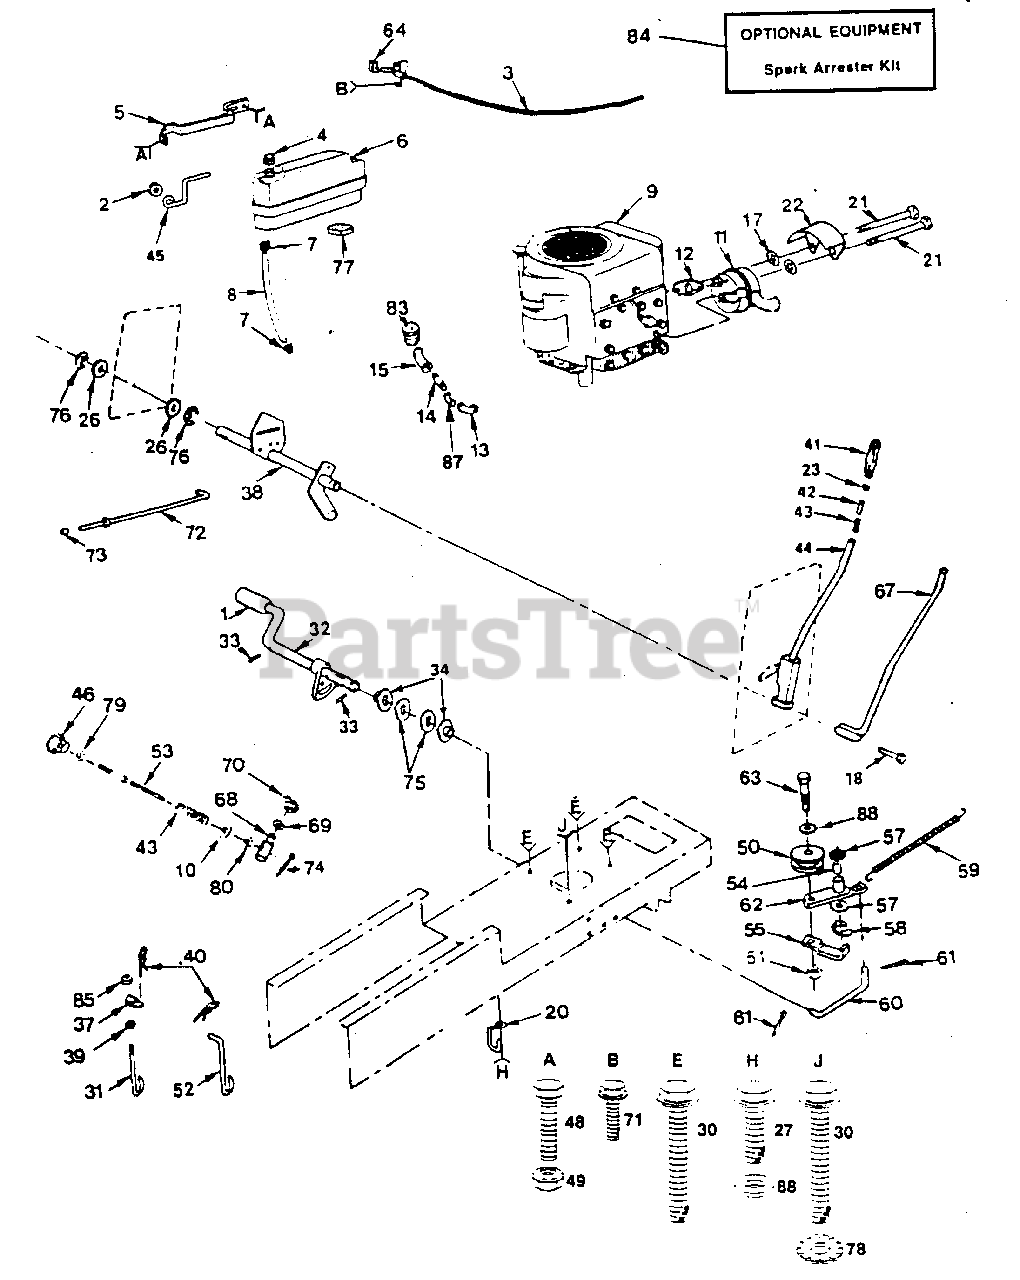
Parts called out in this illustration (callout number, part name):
1	Cover, Pedal
2	Washer, 13/32 x 13/16 x 14 Ga.
3	Control, Throttle
4	Cap, Fuel
5	Support, Tank, Fuel
8	Line, Fuel
9	Engine, Briggs & Stratton, Model No. 281707, Type No. 1413-01
10	Washer 13/32 x 5/8 x 16 Ga.
12	Gasket, Exhaust
13	Elbow, Street
14	Nipple, Pipe, STD 3/8-18 NPT x 3-1/2
15	Elbow, STD 90ø 3/8-18 NPT
17	Washer 15/32 x 1 x 16 Ga.
18	Bolt, Hex 3/8-16 x 1-1/2
20	Retainer, Belt, Chassis, L.H.
21	Bolt, Shoulder
22	Shield, Heat, Muffler
23	Button, Plunger
26	Washer 29/32 x 1-1/4 x 16 Ga.
27	Screw, Hex, Washer Hd., Thd. Roll. 3/8-16 x 3/4
30	Screw, Hex, Washer Hd., Thd. Roll. Type TT 3/8-16 x 1-1/4
31	Link, Lift, Adjustable
32	Shaft, Pedal, Foot
33	Pin, Roll 3/16 x 1
34	Bearing, Nylon
37	Trunnion, Lift
38	Shaft Assembly, Lift
39	Nut, Hex, Jam 7/16-20
40	Retainer, Spring
41	Grip, Handle
42	Plunger, Lever, Hand
43	Spring
44	Lever Assembly, Hand Kit (Inc. 67)
46	Handle, Adjust, Lift
48	Bolt, Hex 5/16-18 x 3/4 Gr. 5
49	Locknut 5/16-18 Gr. B
50	Pulley, Idler
51	Nut 3/8-16
53	Rod, Adjust, Lift
55	Retainer, Belt
57	Washer, Hardened
59	Spring, Return, Clutch
60	Link, Clutch
61	Pin, Cotter 1/8 x 3/4
63	Bolt, Hex 3/8-16 x 1-1/2
64	Knob, Control, Throttle
68	Trunnion, Stop, Depth
69	Washer 15/32 x 3/4 x 16 Ga.
71	Screw, Hex, Washer Hd., Thd. Cut. 1/4-20 x 5/8
72	Rod, Brake, Park
74	Pin, Cotter 3/32 x 1/2
75	Washer 21/32 x 1 x 16 Ga.
78	Washer, Lock, Ext. Tooth 3/8
79	Nut, Hex, Jam 3/8-16
84	Spark Arrester Kit
85	Nut, Jam, Crownlock 7/16-20
87	Elbow, Street, 45ø
88	Washer 13/32 x 13/16 x 16 Ga.
